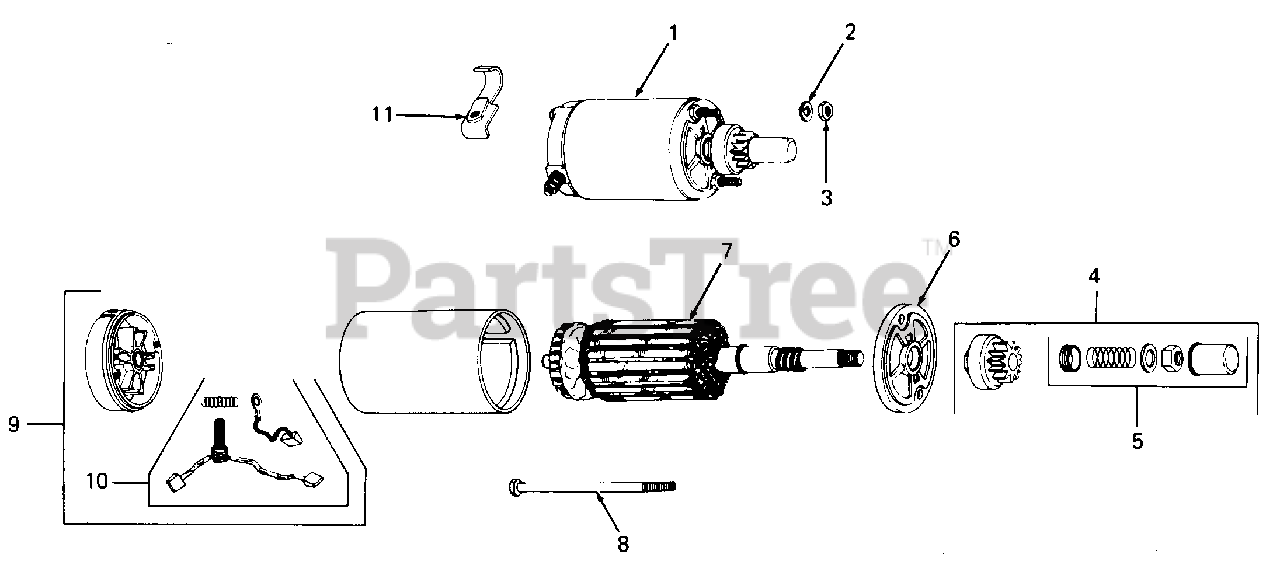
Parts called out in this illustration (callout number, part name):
1	Starter Assembly
2	Washer, Lock, 1/4
3	Nut, Hex, 1/4-20
4	Kit, Drive
5	Kit, Drive Parts
6	Cap, Drive End
8	Bolt, 1/4-20 X 6.87 Lg
9	Cap, Commutator End
10	Kit, Brush
11	Bracket, Mounting Nut
